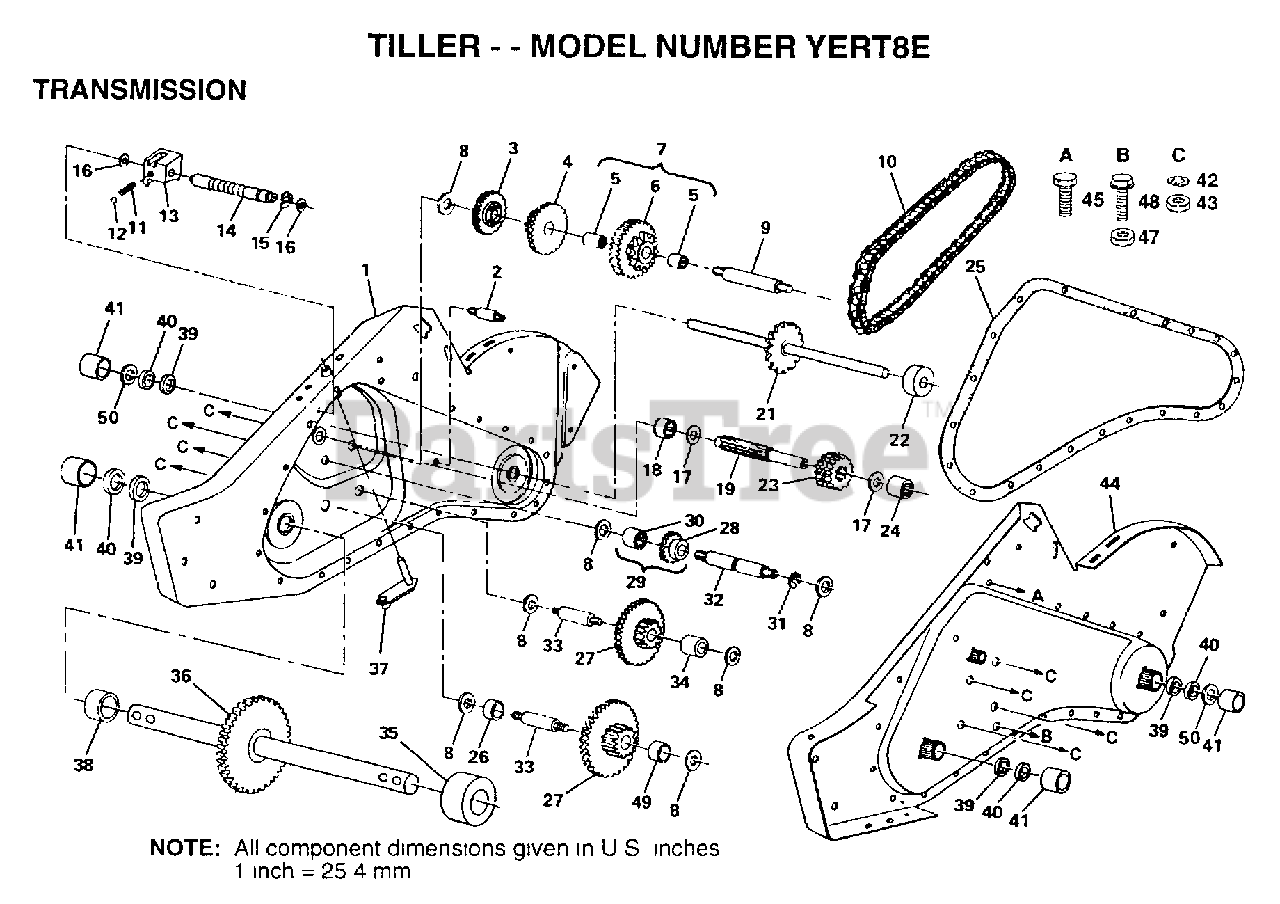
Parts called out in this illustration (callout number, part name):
2	BOLT TI
3	REVERSE GEAR TI
4	CLUSTER GEAR TI
5	"CRT, BEARING"
7	SPROCKET ASSY TI
8	WASHER
9	REDUCTION SHFT TI
10	CHAIN TI
11	SPRING-SHIFT CRT
13	SHIFT FORK TI
14	SHIFT SHAFT TI
15	KLIP RING
16	WASHER SEAL CRT
17	"T, BEARING"
18	"TI, BEARING"
19	SHAFT INPUT
21	SHAFT TINE CRT
22	SPACER CRT
23	INPUT PINION TI
24	NEEDLE BRNG LT
25	GEARCASE GSKT TI
26	SPACER CRT
27	GEAR CLUSTER CRT
28	REVERSE GEAR TI
29	GEAR ASSY TI
30	NEEDLE BEARING TI
31	KLIP RING
32	REVERSE SHAFT TI
33	SHAFT CRT
34	SPACER CRT
35	SPACER CRT
36	SHAFT ASSY CRT
37	BRACKET ASM SHIFT
38	SPACER CRT
39	OIL SEAL STD
40	SEAL RING RUBBER
41	CUP.FORMED.
42	LOCKWASHER
43	NUT.ASF.HEX.7/16
45	SCREW 5/16-18X5/8
47	NUT.HEX.5/16-18
48	BOLT TI
49	SPACER CRT
50	RING SPIRAL CRT
